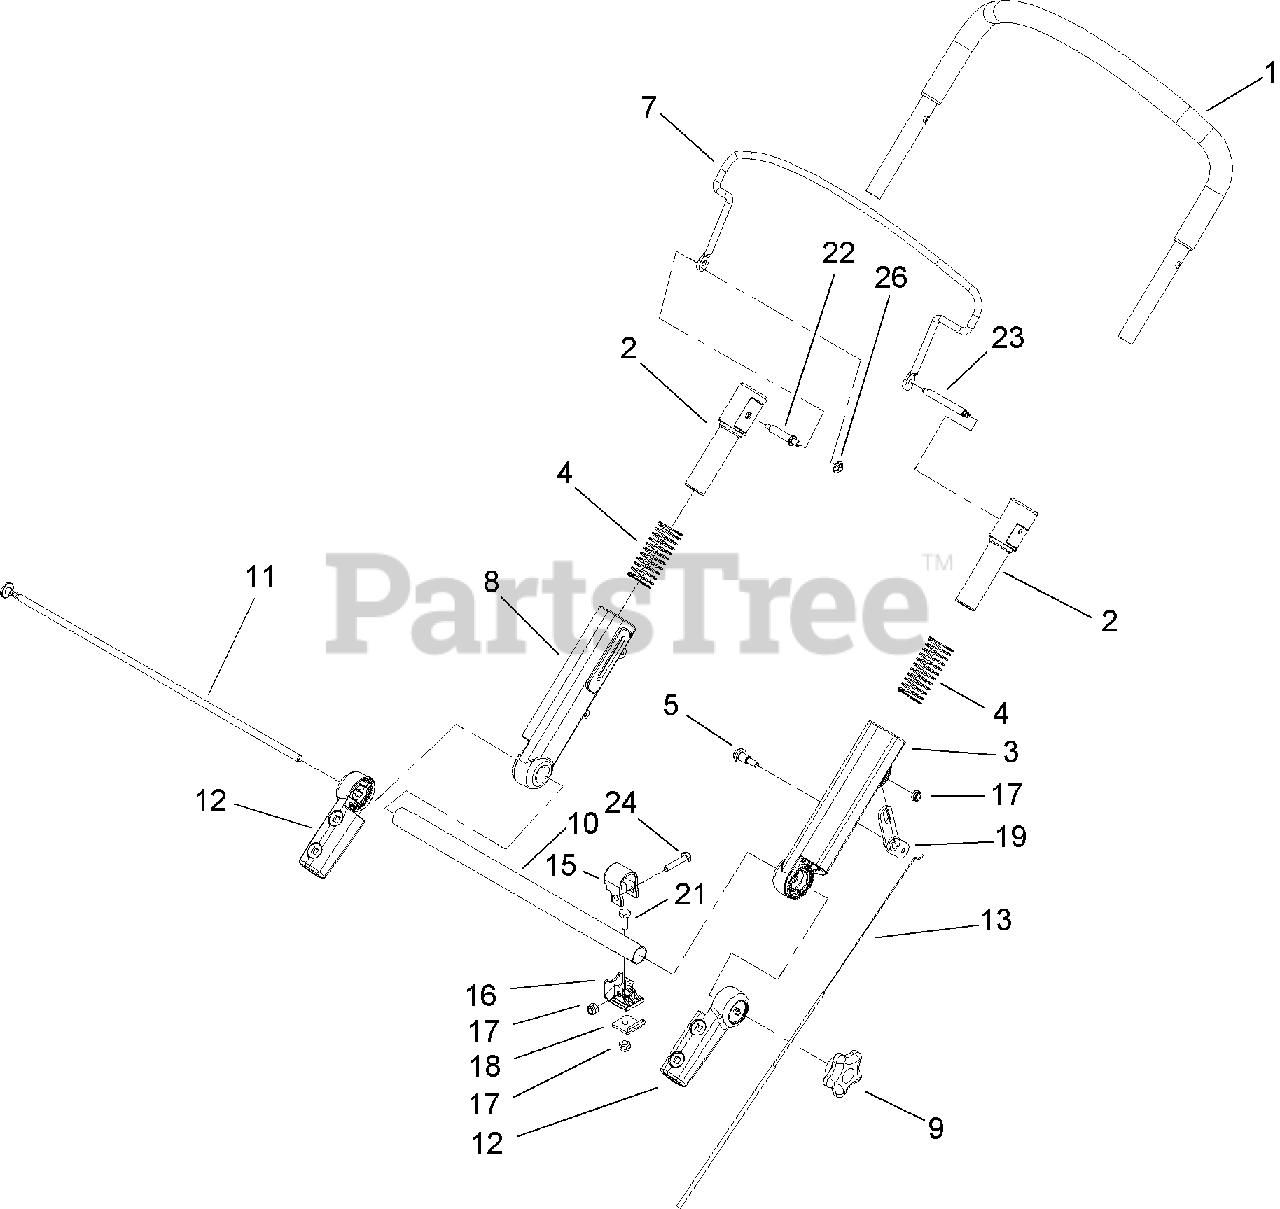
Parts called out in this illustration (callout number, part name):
1	UPPER HANDLE ASM
2	SLEEVE-HANDLE
3	SLIDE-TOP, LH
4	SPRING-COMPRESSION
5	BOLT-SHOULDER
7	BAIL-BRAKE
8	SLIDE-TOP, RH
11	ROD-THREADED
12	MOUNT-HANDLE, LOWER
13	CABLE-TRACTION
15	SUPPORT-CABLE
16	SUPPORT-GUIDE, CABLE
17	NUT-LOCK, NI
18	CLAMP-CABLE
19	LEVER-TRACTION
21	SCREW-HH
22	PIN-HANDLE
23	PIN-HANDLE, BBC
24	SCREW-CARR
26	RETAINER-PUSH ON
